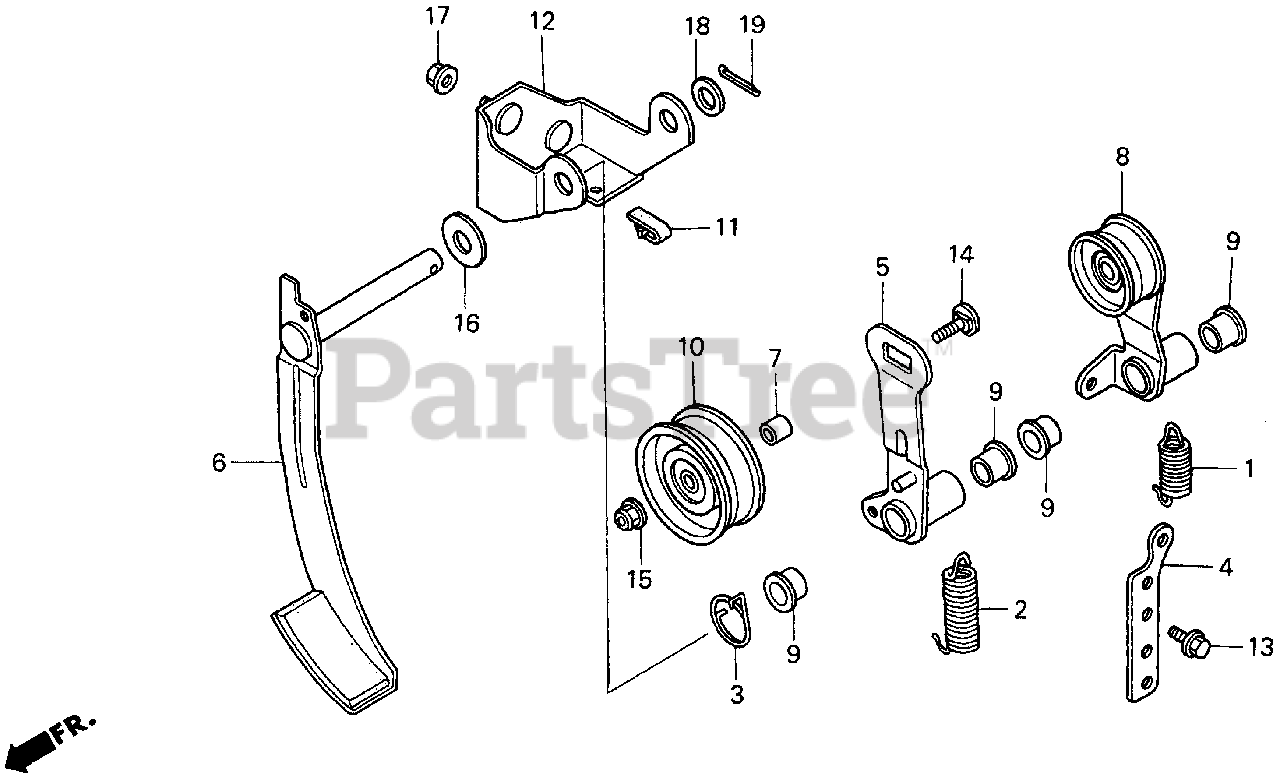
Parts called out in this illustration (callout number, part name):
1	SPRING, WHEEL TENSION RETURN
2	SPRING, AUGER TENSIONER RETURN
3	SPRING, BRAKE ARM
4	STAY, TENSIONER SPRING
5	ARM, AUGER TENSIONER
6	ARM, AUGER BRAKE
7	COLLAR, ROLLER
8	ARM, WHEEL TENSIONER
9	BUSH, TENSIONER ARM
11	RUBBER, STOPPER
12	BRACKET, TENSION ARM
13	BOLT, FLANGE (6X12) (CT200)
14	BOLT, ROLLER
15	NUT, SELF-LOCK (8MM) (CLINCH)
16	WASHER, BRAKE ARM
17	NUT, FLANGE (8MM)
18	WASHER, PLAIN (12MM)
19	PIN, SPLIT (3.0X18)
